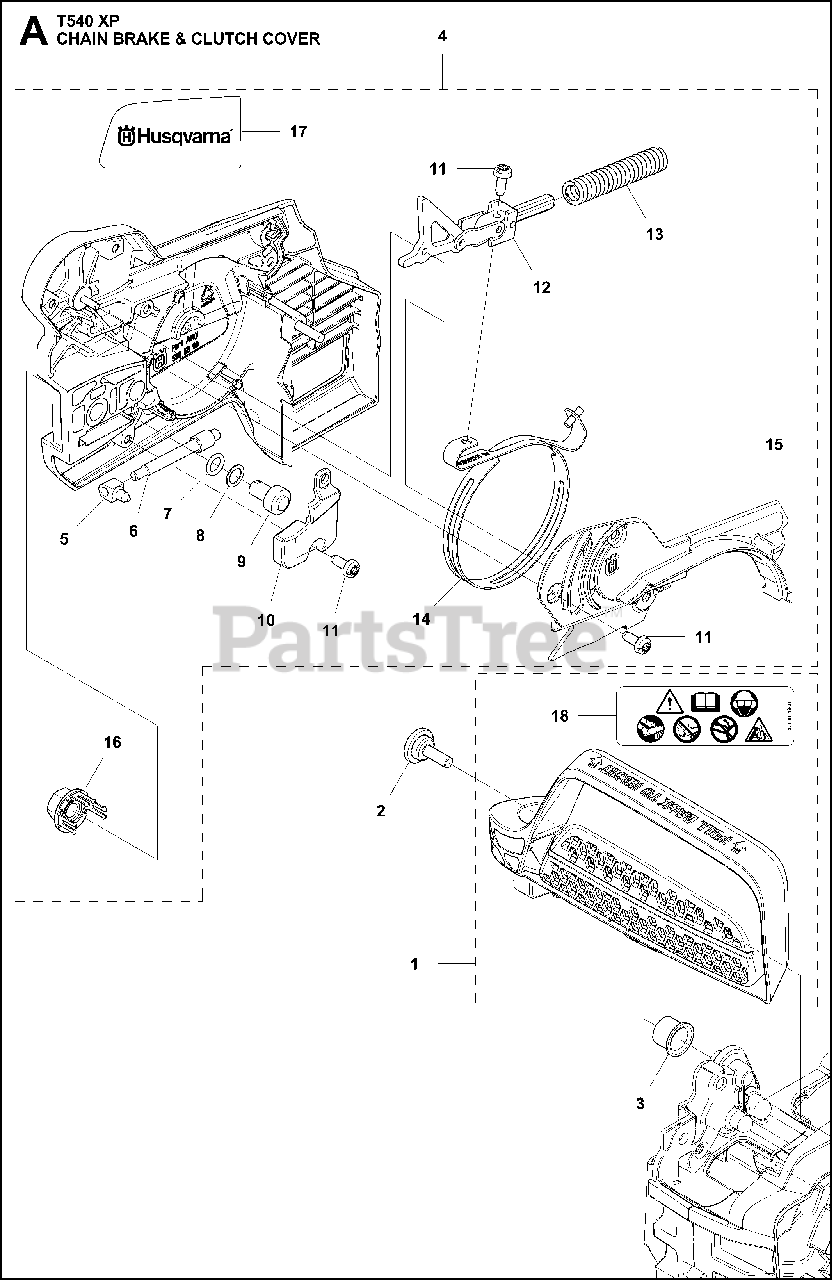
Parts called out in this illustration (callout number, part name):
1	HAND GUARD ASSY
4	CLUTCH COVER ASSY
5	PAWL
6	SCREW
7	O-RING
8	WASHER
9	WORM WHEEL
10	COVER LID
11	SCREW CITXPANT
12	KNEE JOINT ASSY
13	BRAKE SPRING
14	BRAKE BAND ASSY
15	COVER BRAKE COVER
16	NUT RETAINER ASSY
17	DECAL
18	DECAL
